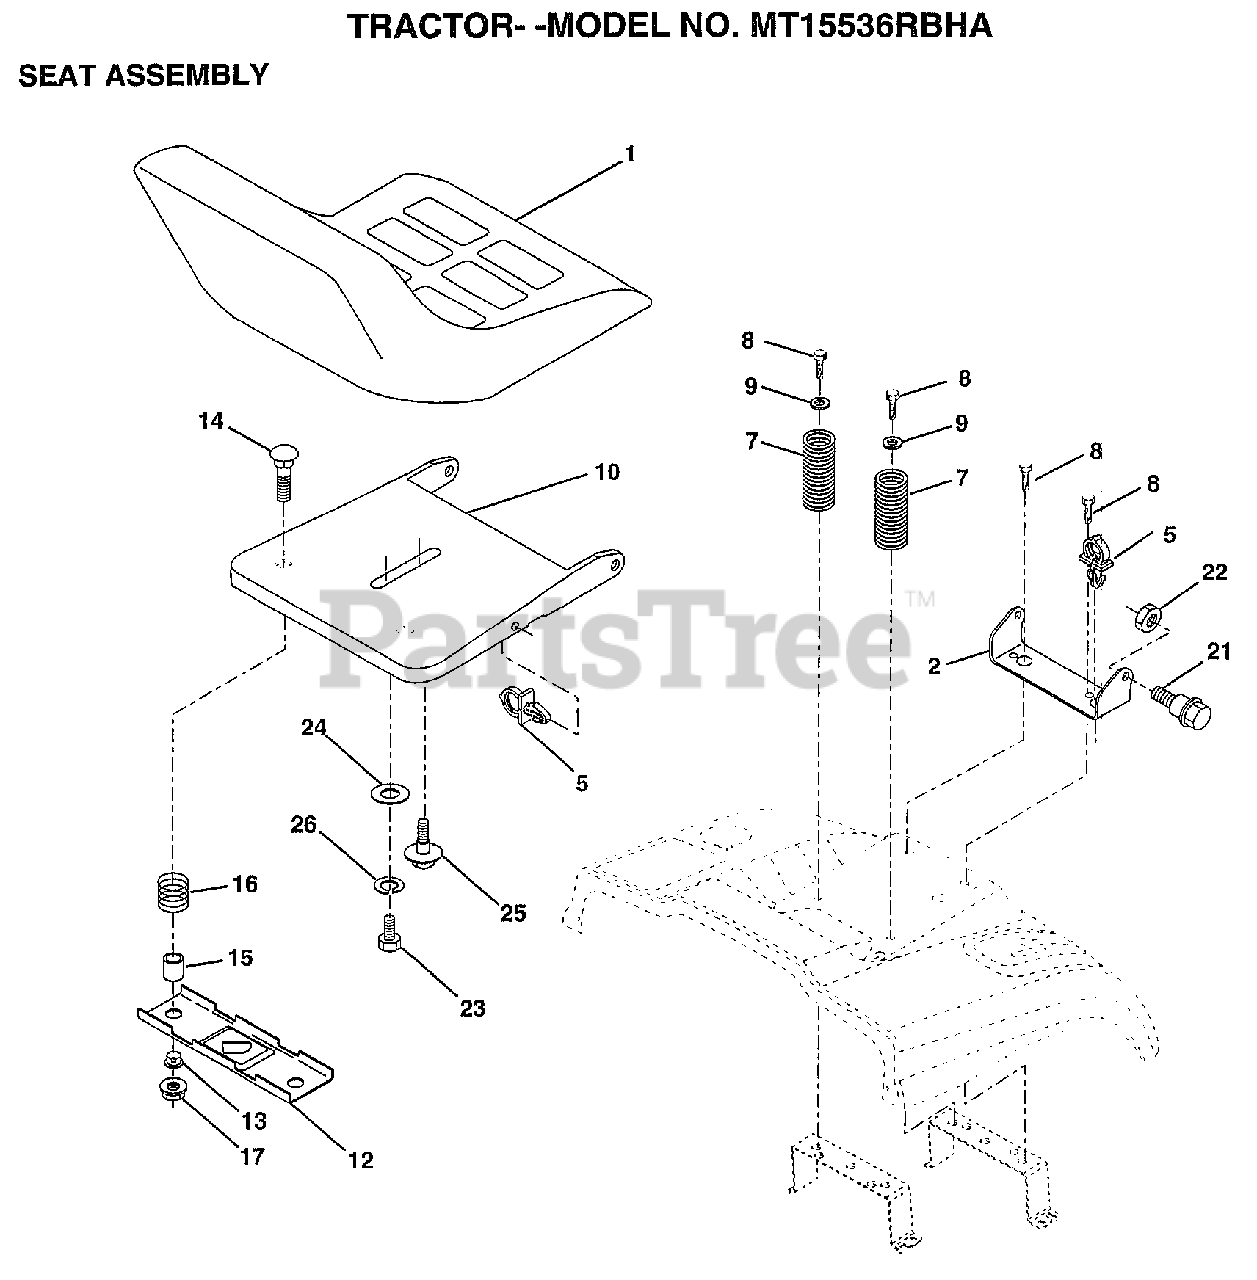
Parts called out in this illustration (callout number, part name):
1	SEAT.2400/1416.BK
2	BRACKET PVT SEAT
5	CLIP.PUSH-IN.HING
7	SPRING COMPRESSIO
8	SCREW GTV
9	WASHER
10	PAN-SEAT
12	BRKT SWITCH
13	BUSHING
14	BOLT-RD HD SQ NK
15	SPLIT SPACER
16	SPRING
21	"BOLT,SHOULDER"
22	NUT
23	BOLT
24	WASHER
25	"BOLT,SHOULDER"
26	LOCKWASHER
